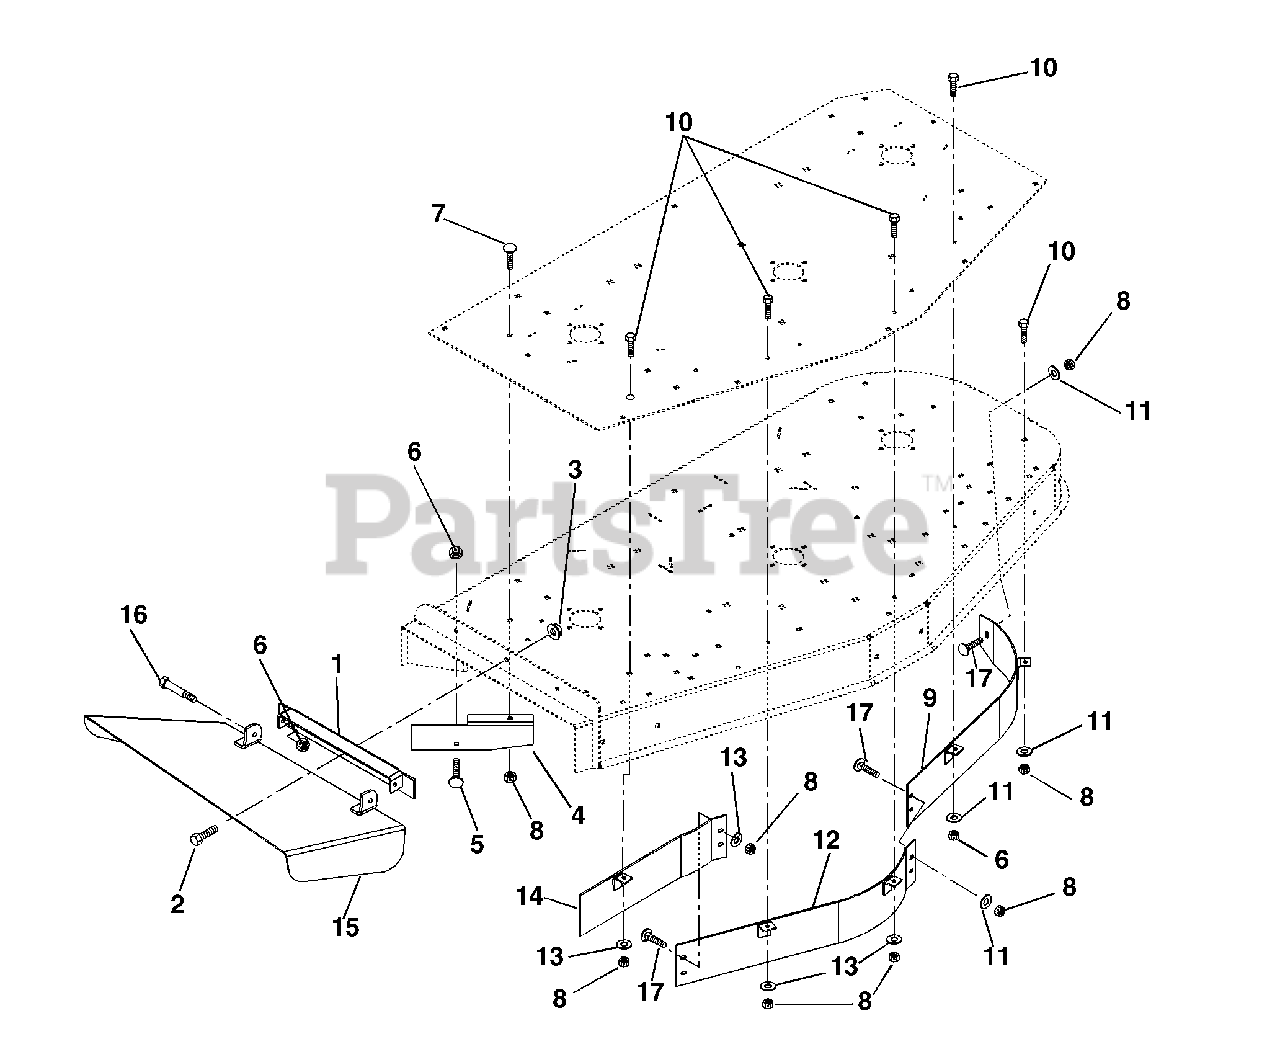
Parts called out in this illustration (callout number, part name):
1	Weldment, Discharge Chute Bracket
2	Bolt-Hex .38-16 x 1.00 Grade 5
3	Nut-Locking-Flange .38-16
4	Deflector, 72"
5	Bolt-Round Head Square Neck .38-16 x 1.00 Grade 2
6	Nut-Locking-Center .38-16
7	Bolt-Round Head Square Neck .31-18 x 1.00 Grade 5
8	Nut-Locking-Nylon .31-18
9	Weldment, 72" Left Hand Baffle
10	Bolt-Hex .31-18 x 1.00 Grade 5
11	Washer-Flat-Steel .312 x .734 x .065
12	Weldment, 72" Center Baffle
13	Washer-Flat-Steel .312 x .734 x .065
14	Weldment, 72" Right Hand Baffle
15	Weldment, Discharge Chute 72"
16	Bolt-Shoulder .38-16 x .38
17	Bolt-Round Head Square Neck .31-18 x .75 Grade 2
18	72" S.D. Mulch Kit
19	72" Discharge Cover Kit
